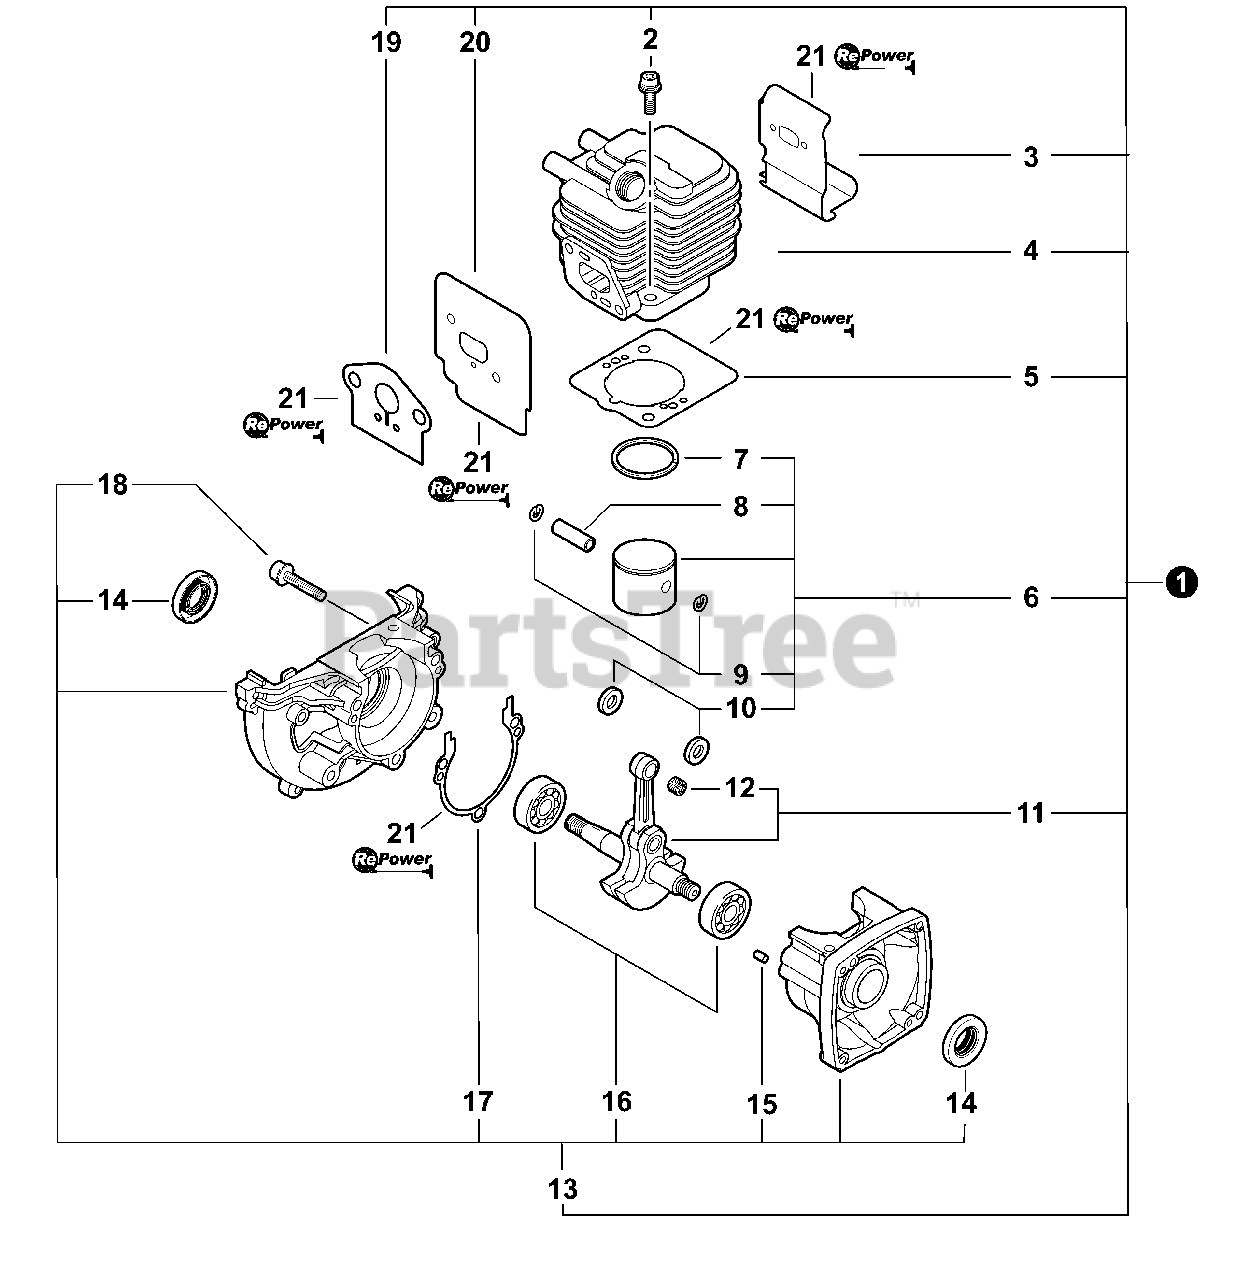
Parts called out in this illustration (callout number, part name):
1	SHORT BLOCK -- SB1096
2	SCREW - 5×22
3	SHIELD, EXHAUST
4	CYLINDER
5	GASKET, CYLINDER
6	PISTON KIT
7	RING, PISTON
8	PIN, PISTON
9	RING, RETAINING
10	SPACER, PISTON
11	CRANKSHAFT ASSY
12	BEARING, NEEDLE - 8
13	CRANKCASE KIT
14	SEAL, OIL
15	PIN, LOCATING - 4×8
16	BEARING, BALL - 6201
17	GASKET, CRANKCASE
18	SCREW - 5×28
19	GASKET, INTAKE
20	SHIELD, INTAKE
21	GASKET KIT
